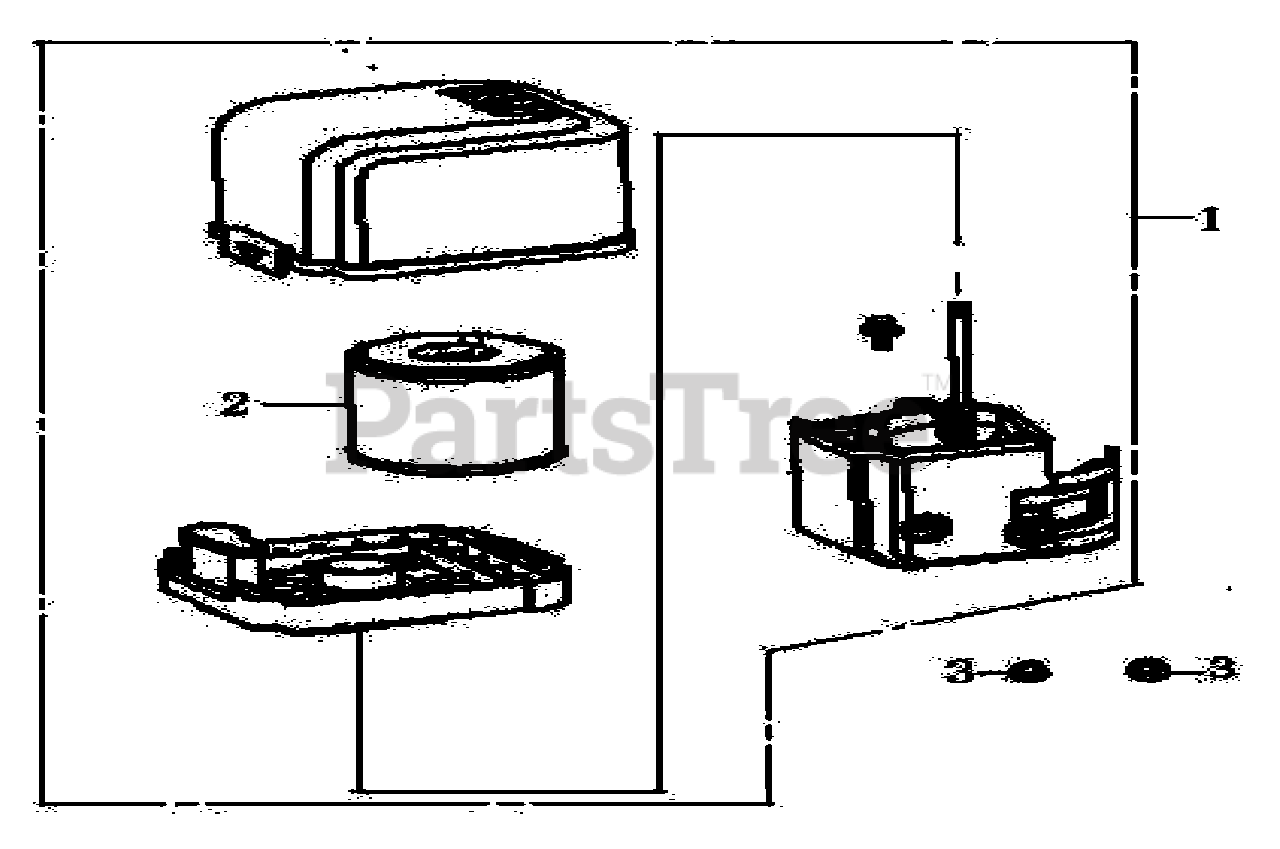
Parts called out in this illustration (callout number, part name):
1	AIR CLEANER ASSY
2	ELEMENT, AIR CLEANER
3	NUT, FLANGE, M6
